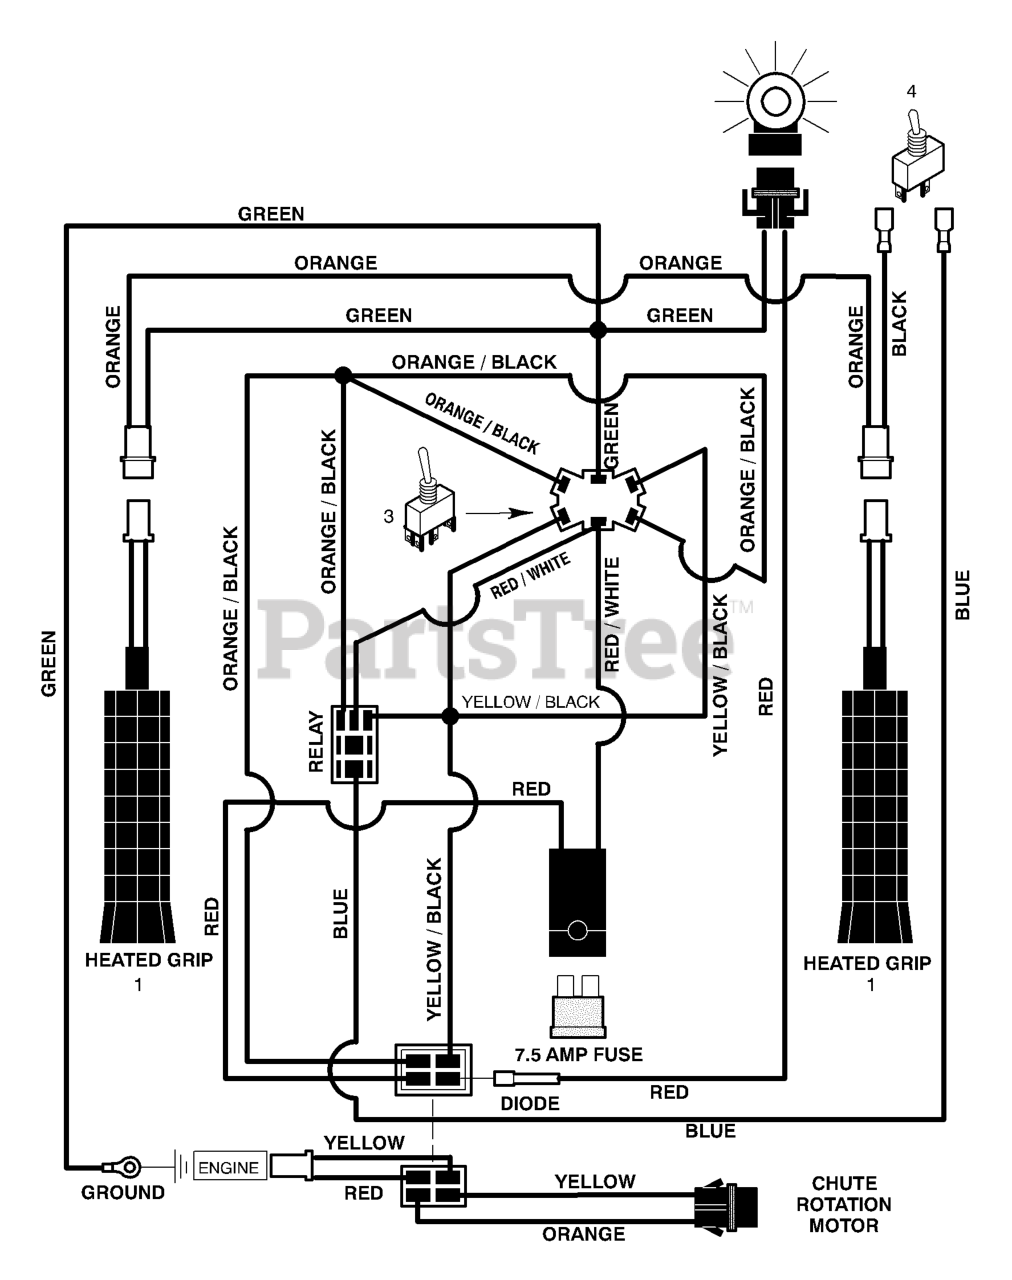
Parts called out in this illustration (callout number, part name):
1	GRIP, HEATED
3	SWITCH, CHUTE ROTATION
4	SWITCH, HEATED GRIP
